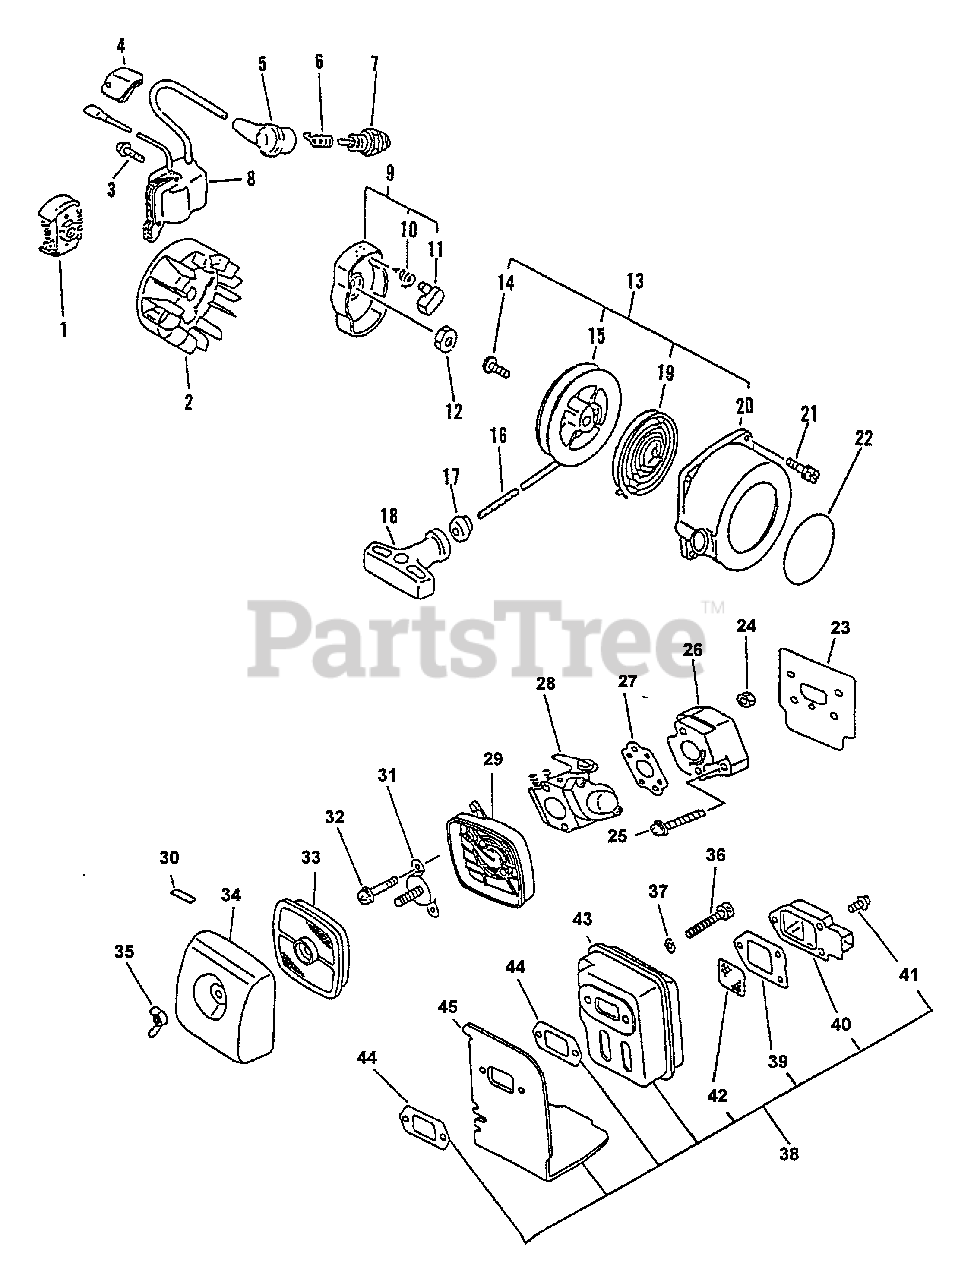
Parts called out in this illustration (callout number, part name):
1	CLUTCH ASSY
2	FLYWHEEL
3	BOLT 4×20
5	CAP, SPARK PLUG
6	TERMINAL, SPARK PLUG
7	SPARK PLUG
8	COIL, IGNITION
9	PAWL ASSY, STARTER
10	SPRING, RETURN
11	PAWL, STARTER - BLACK
12	NUT 8×1.25
13	STARTER ASSY
14	SCREW
15	REEL, ROPE
17	GUIDE, ROPE
18	GRIP, STARTER
19	SPRING, RECOIL
20	CASE, RECOIL STARTER
21	LABEL, ECHO
22	SCREW 4×16
23	HEAT SHIELD, INTAKE
24	NUT M5
25	SCREW 5×20
26	INSULATOR, INTAKE
27	GASKET, INTAKE
28	CARBURETOR - C1U-K34
29	AIR FILTER CASE ASSY
30	LABEL, CHOKE
31	PLATE, PREVENT
32	SCREW 5×65
33	FILTER, AIR - SINGLE LAYER
34	COVER, AIR FILTER
35	WINGNUT - 6
36	BOLT 5×55
37	WASHER, FLAT 5.5×10×0.8
38	MUFFLER ASSY
39	GASKET, EXHAUST
40	GUIDE, EXHAUST - INNER
41	SCREW 4×10
42	SCREEN, SPARK ARRESTER
43	MUFFLER ASSY
44	GASKET, EXHAUST
45	COVER, EXHAUST
